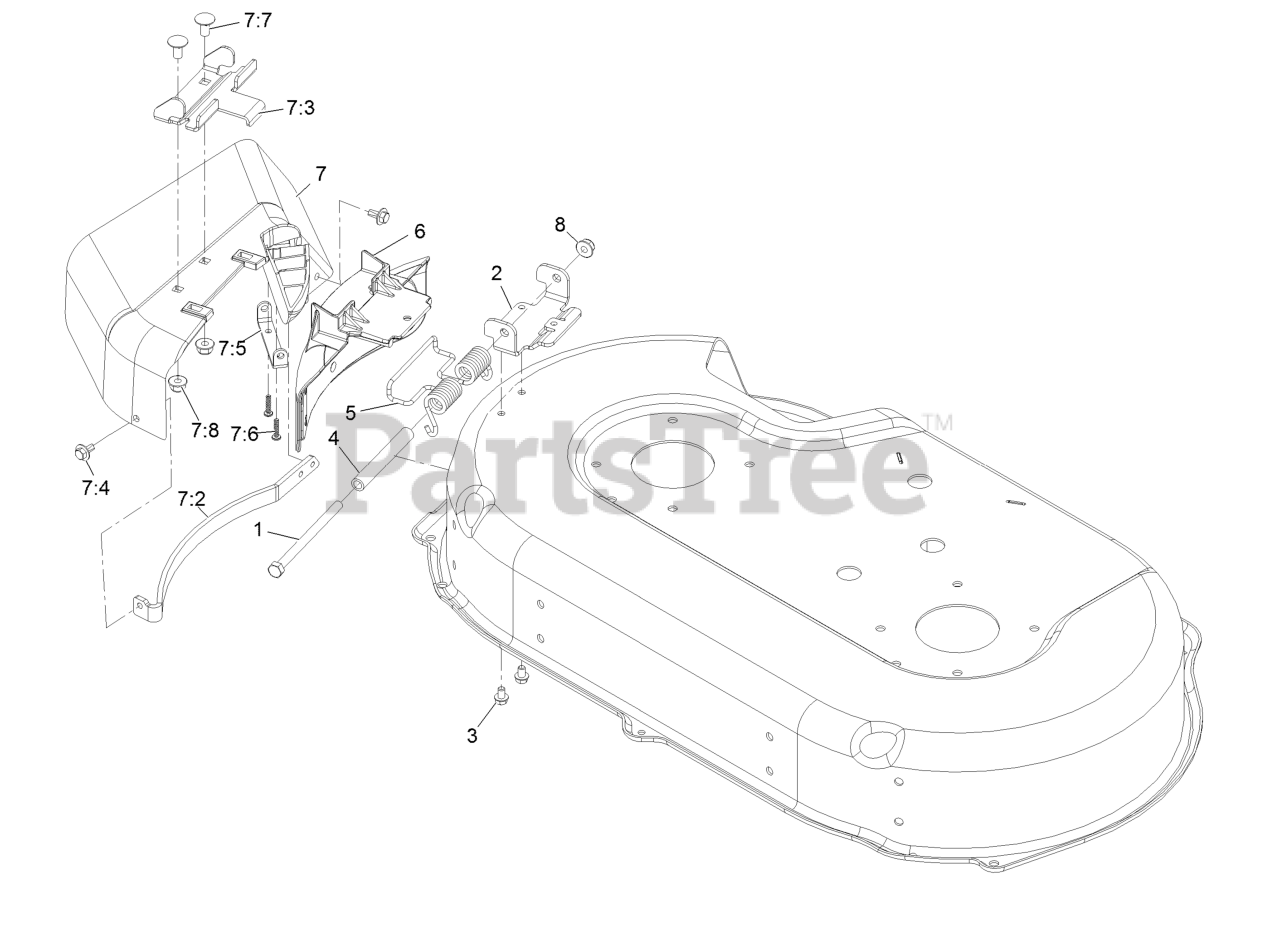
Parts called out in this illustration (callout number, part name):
1	SCREW-HH
3	SCREW-HWH
5	SPRING-TORSION
6	COVER-DISCHARGE
7	SIDE DISCHARGE CHUTE ASM
7:2	GUARD-CHUTE
7:3	BRACKET-CHUTE
7:4	SCREW-HHFTF
7:5	BRACKET-COVER
7:6	SCREW-PPH
7:7	SCREW-CARR
7:8	NUT-HF, NI
8	NUT-HF, NI
